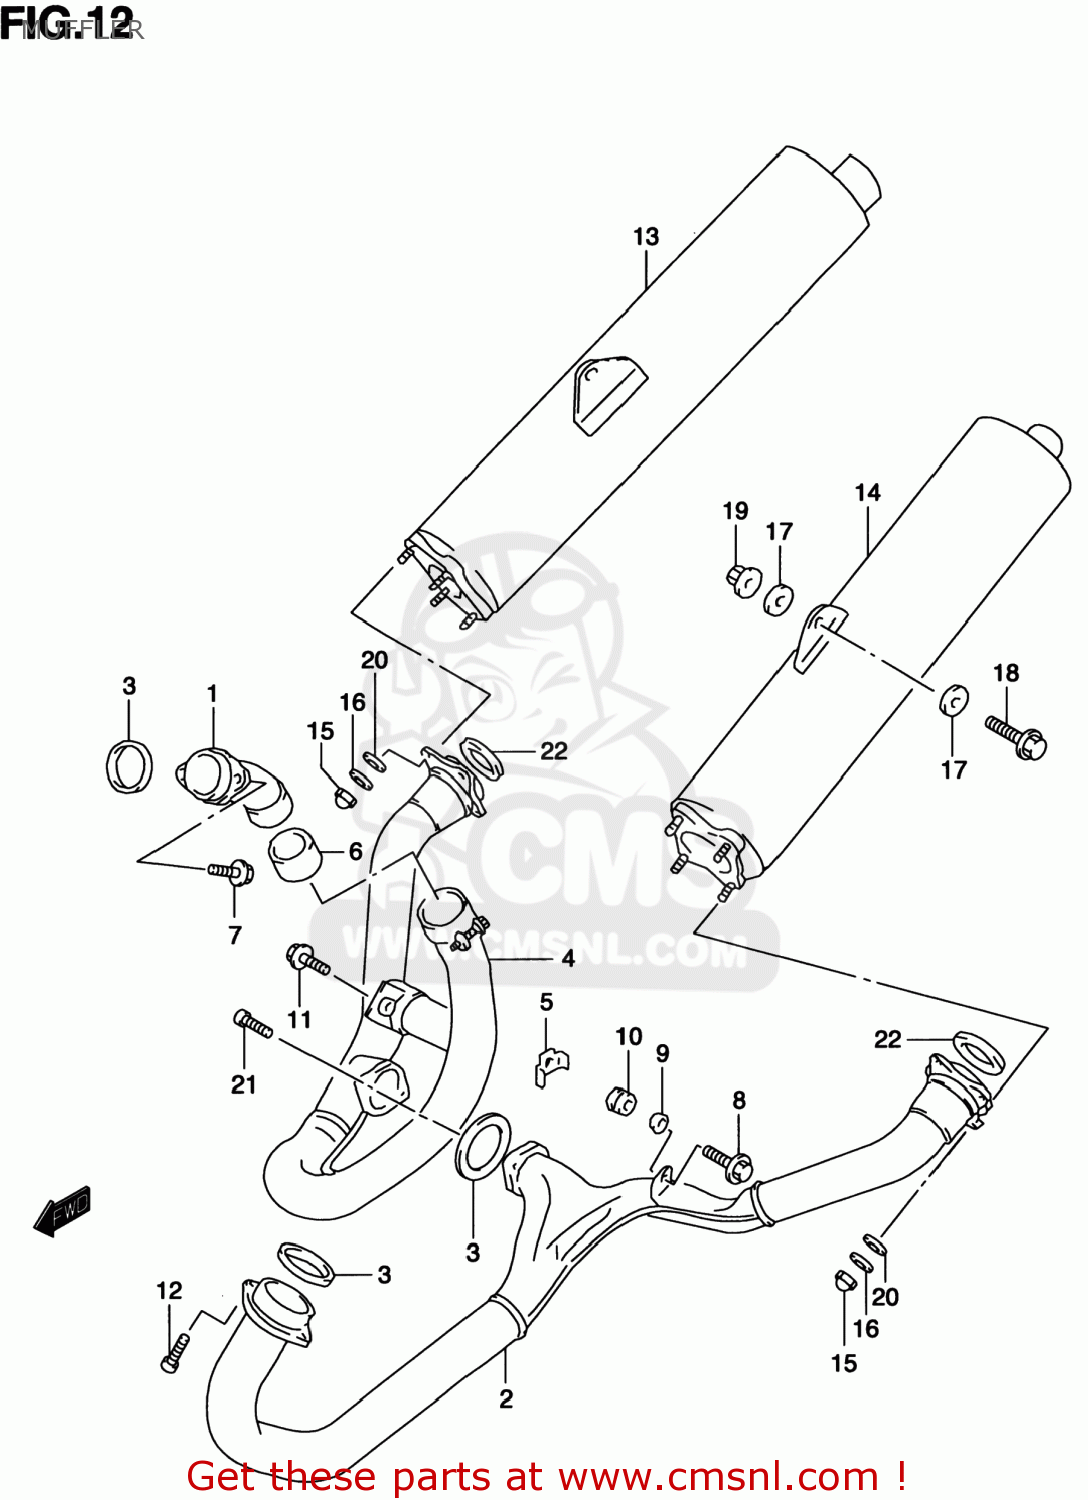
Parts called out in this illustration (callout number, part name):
1	PIPE,EXHAUST,R
2	PIPE,EXHAUST,L
3	GASKET,EXHAUST PIPE (NAS)
4	PIPE,EXHAUST JOINT,R
5	SPROCKET,EXHAUST,L
6	CONNECTOR,EXHAUST,R
7	BOLT
8	BOLT 8X45
9	SPACER(8.6X12X24.2)
10	CUSHION
11	BOLT
12	BOLT
13	BODY,MUFFLER,R
14	BODY,MUFFLER,L
15	NUT
16	WASHER(8.5X18X1.6)
17	WASHER (8.5X24X1.6)
18	BOLT
19	NUT
20	O RING(D:1.9,ID:7.8)
21	BOLT,EXH MANF
22	GASKET,MUFFLER JOINT (NAS)
